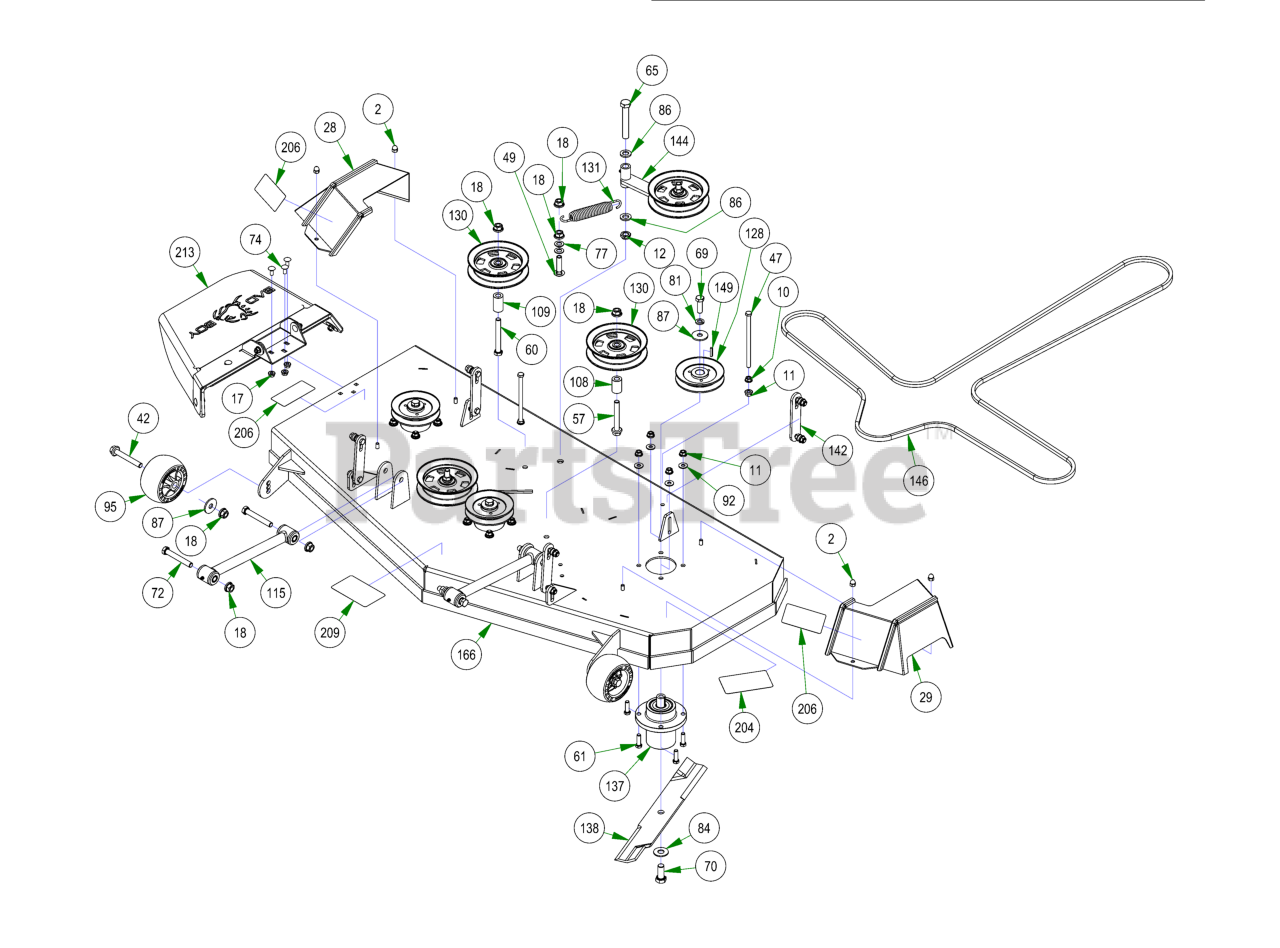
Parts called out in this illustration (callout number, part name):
2	5/16-18 ACORN NUT HIGH-CROWN ZC
10	3/8-16 HEX SERRATED FLANGE NUT HARD/ZINC
11	3/8-16 NYLON INSERT FLANGE LOCKNUT (GR.F) ZINC
12	5/8-11 NYLON INSERT JAM LOCKNUT ZINC
17	5/16-18 NYLON INSERT FLANGE LOCKNUT ZINC
18	1/2-13 NYLON INSERT FLANGE LOCKNUT ZINC
28	2021 Maverick 54”/60” RH Pulley Cover
29	2021 Maverick 54”/60” LH Pulley Cover
42	1/2-13 X 90MM HEX FLANGE BOLT W/SHOULDER (GR.8) ZINC
47	3/8-16 X 6.5 HEX CAP SCREW (GR.5) ZINC
49	1/2-13 X 2 CARRIAGE BOLT ZINC
57	1/2-13 X 3-1/2 HEX FLANGE BOLT (GR.8) ZINC
60	1/2-13 X 4 HEX CAP SCREW (GR.8) ZINC YELLOW
61	3/8-16 X 1-1/4 HEX CAP SCREW (GR.5) ZINC
65	5/8-11 X 4 HEX CAP SCREW (GR.8) ZINC YELLOW
69	1/2-20 X 1-1/2 HEX CAP SCREW (GR.5) ZINC
70	5/8-18 X 1-1/2 HEX CAP SCREW (GR.8) ZINC YELLOW
72	1/2-13 X 3-1/2 HEX CAP SCREW (GR.5) ZINC
74	5/16-18 x 3/4 Carriage Bolt
77	.517 SQ WDTH ID X .937 OD X .060 THICK F/W PHOS/OIL
81	1/2 SPLIT LOCKWASHER (GR.8) ZINC/YELLOW
84	5/8 USS FLAT WASHER (1-3/4" OD) GR.8 ZINC YELLOW
86	.635 ID X 1.120 OD X .140 THICK FLAT WASHER NYLON
87	1/2 BELLEVILLE WASHER (1-5/8 OD X .140 THK) ZINC
92	5/16 USS FLAT WASHER (7/8 OD) ZINC
95	Deck Wheel
108	.502 ID X .750 OD X 1.500 Long Spacer
109	1 3/4" Pulley Spacer
115	Hybrid Turnbuckle/Deck Locator
128	54 MZ Spindle Pulley
130	5-3/4 Idler Pulley
131	Deck Idler Spring
137	Spindle Assembly-MZ
138	54" MZ Fusion Blade
142	Deck Hanger Assembly
144	2017 54"/48" Deck Idler Assembly
146	B155.75 Deck Belt
149	3/16 X 1 SQ MACHINERY KEY 1018 STL ZINC
166	2017 54" MZ Magnum Deck
204	2018 54" Deck Decal
206	Danger Decal-Spindle/Discharge
209	Deck Belt Route Decal
213	MZ Discharge Chute Assembly
